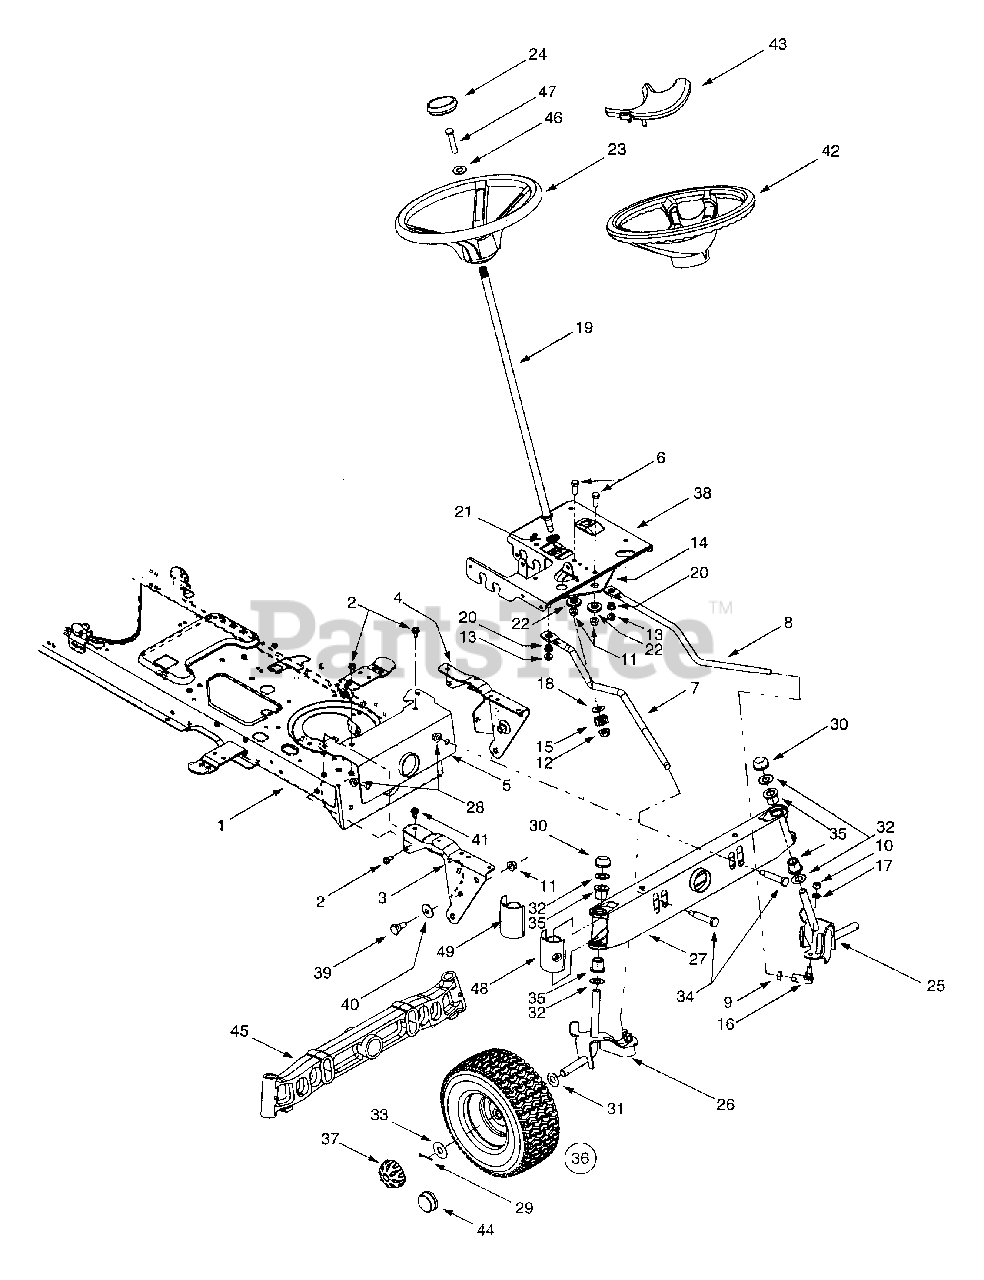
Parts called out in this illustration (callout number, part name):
6	Hex Cap Screw, 3/8-16 x 1 (Grade 5)
7	RH Drag Link
8	LH Drag Link
9	Jam Nut, 7/16-20 (Grade 2)
10	Hex Nut, 3/8-24 (Grade 2)
11	Flange Lock Nut, 3/8-16
12	Flange Lock Nut, 7/16-20
13	Flange Lock Nut, 5/16-18
14	Steering Gear, 11/90 Ratio
15	Steering Pinion Gear
16	Ball Joint, 7/16-20
17	Lock Washer, 3/8
18	Flat Washer, .51 x 1.12 x .06
19	Steering Shaft, .625 OD x 24.4
20	Plastic Bushing, .38 ID
21	Hex Flange Bearing, 5/8
22	Shoulder Spacer, .38 ID
23	Standard Steering Wheel, 13.25
24	Steering Wheel Cap, Round
25	LH Axle Assembly, .625 Diameter
25	LH Axle Assembly, .625/.750 Diameter
26	RH Axle Assembly, .625 Diameter
26	RH Axle Assembly, .625/.750 Diameter
28	Flange Lock Nut, 3/8-16
29	Cotter Pin
30	Push Cap, .625
31	Flat Washer, .64 x 1.0 x .12
32	Flat Washer, .64 x 1.24 x.06
32	Flat Washer, .78 x 1.589 x .06
33	Flat Washer, .635 x 1.589 x .06
34	Shoulder Screw, .5 x 2.2, 3/8-16
35	Flange Bearing, .632 ID x .937 OD
35	Flange Bearing, .76 ID x .937 OD
37	Deluxe Hub Cap
39	Shoulder Screw, 3/8-16
40	Bell Washer, .39 x 1.13 x .062
41	Self-tapping Screw, 5/16-18 x .75
42	Deluxe Steering Wheel
43	Steering Wheel Cap, w/ Icon
44	Standard Hub Cap
45	Cast Iron Pivot Bar
46	Bell Washer, .34 x .872
47	Hex Bolt, 5/16-18 X 1
48	Pivot Bar End Cap w/ Fitting
49	Pivot Bar End Cap w/o Fitting
